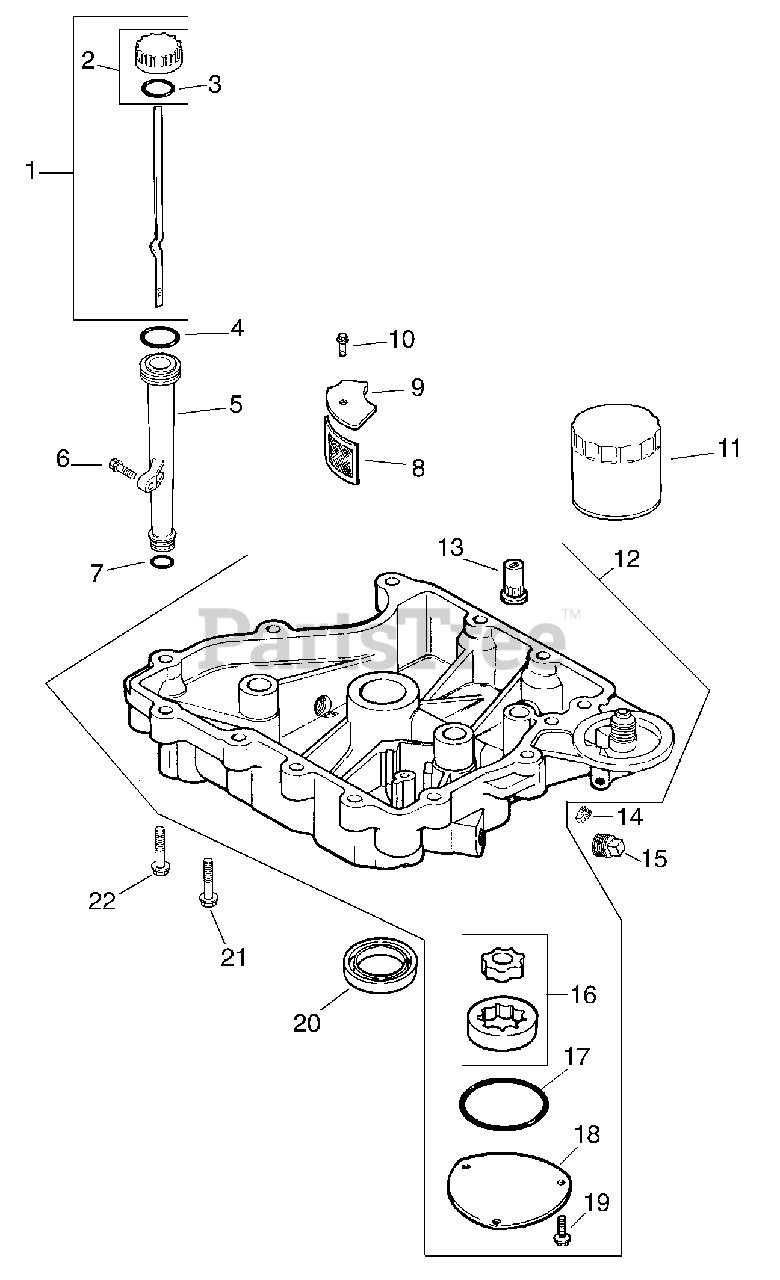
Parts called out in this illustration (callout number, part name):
1	Dipstick
2	Kit, Oil Fill Cap
3	O-ring
4	O-ring, Upper Oil Fill Tube
5	Tube, Oil Fill
6	Screw, Hex. Flange M6 x 1.0 x 25
7	O-ring, Lower Oil Fill Tube
8	Screen, Oil Pickup
9	Cover, Oil Pickup Screen
10	Screw, Hex. Flange M5 x 0.8 x 16
11	Filter, Oil
12	Pan, Oil
13	Valve, Oil Pressure Relief
14	Plug, Sq. Hd. 1/8"
15	Plug, Sq. Hd. Solid 3/8"
16	Pump Assembly, Oil
17	O-ring, Oil Pump Cover
18	Cover, Oil Pump
19	Screw, Hex. Flange M5 x 0.8 x 16
20	Seal, Oil (P.T.O. End)
21	Screw, Hex. Flange M8 x 1.25 x 45
22	Screw, Hex. Flange M8 x 1.25 x 45
